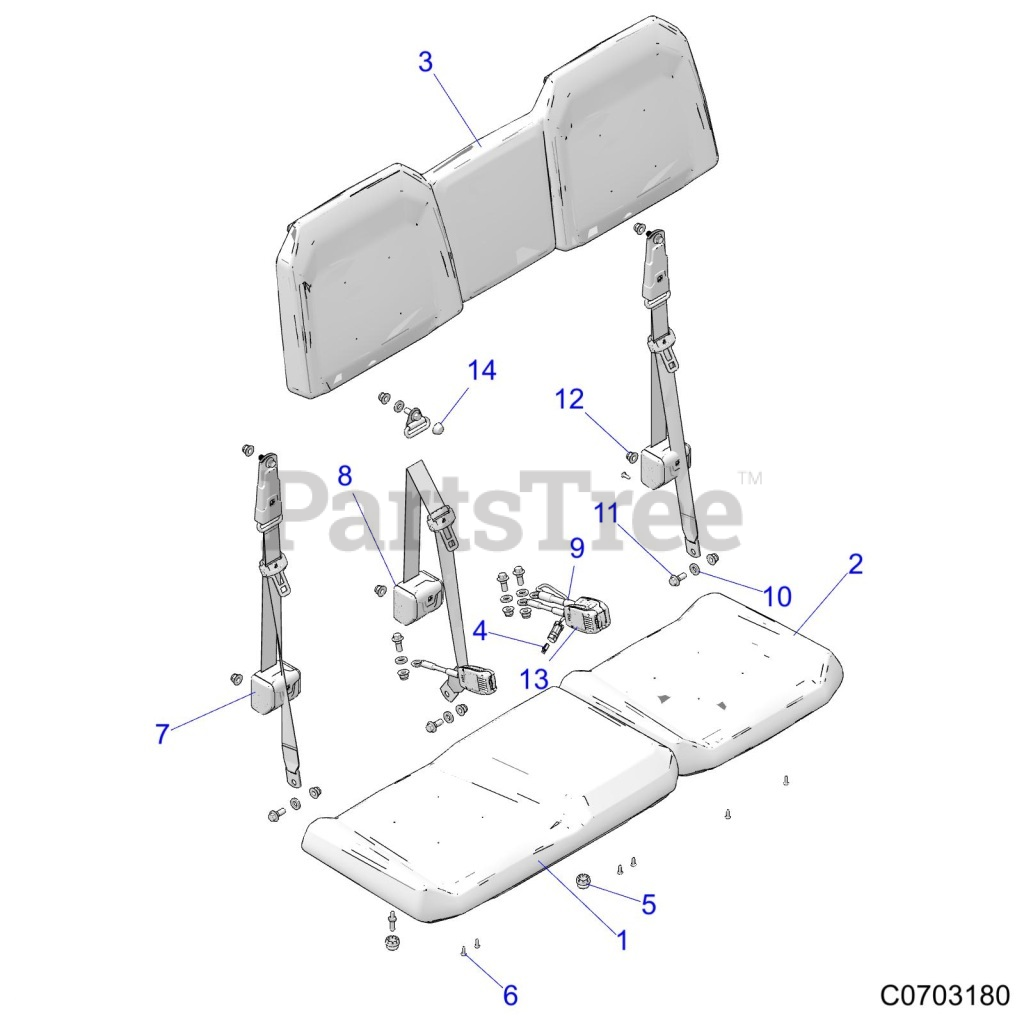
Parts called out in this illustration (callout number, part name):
1	ASM-SEAT,BTM,60,VINYL,GUNMETAL
2	ASM-SEAT,BTM,40,VINYL,GUNMETAL
3	ASM-SEAT,3PASS,BACK,GUNMETAL
4	CLIP-CONNECTOR,6.35MM HOLE
5	BUMPER-RUBBER
6	SCR-TX TRUSS-#14X3/4,HI/LO ZBK
7	ASM-SEAT BELT,3PT
8	ASM-SEAT BELT,3PT,CENTER
9	BUCKLE, SEATBELT, 90, SWITCH
10	WASHER-SEATBELT,RUBBER
11	SCR-HXFLSH-M12X1.75-M14X9 ZOD
12	NUT-HXFL M12X1.75 NYLOC ZOD
13	BUCKLE-SEATBELT,9.6,PASSENGER
14	CAP-BOLT HEAD
